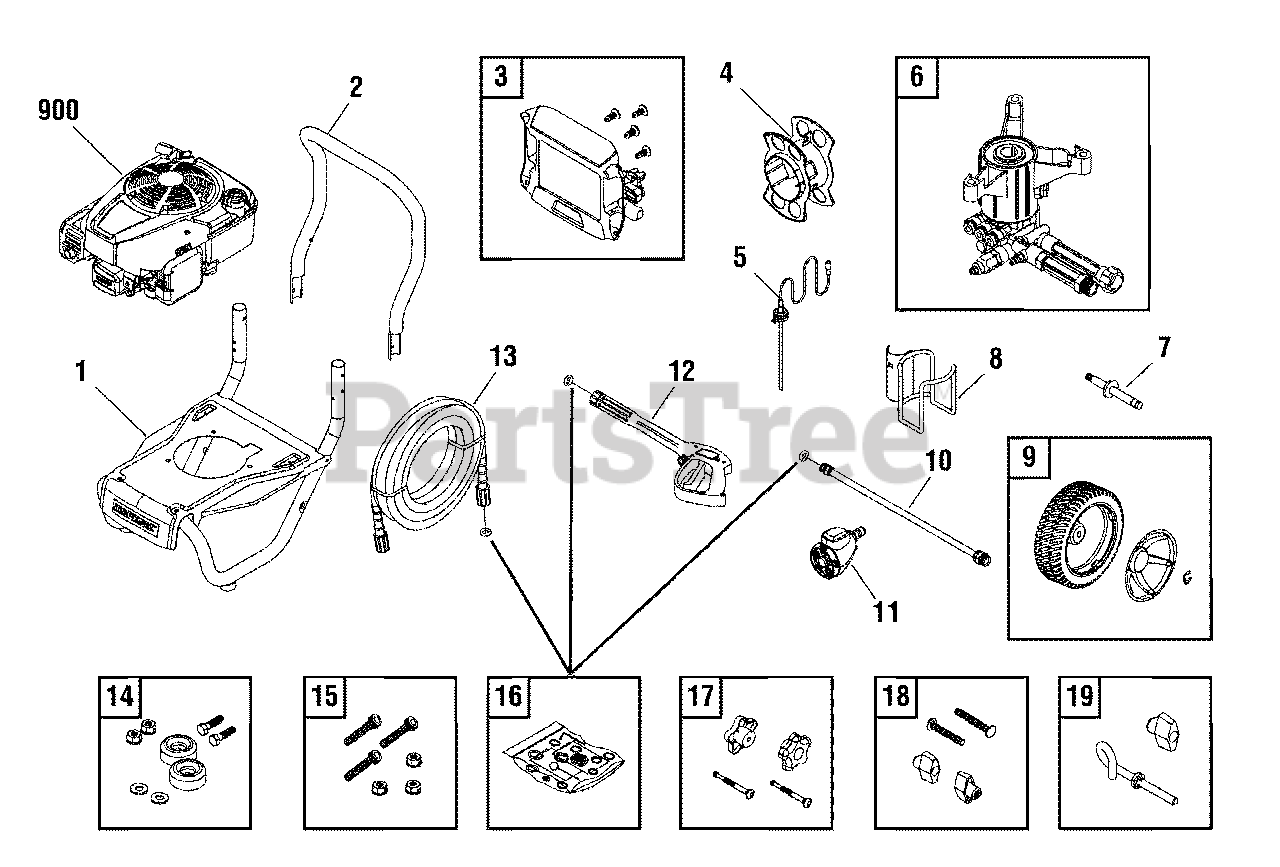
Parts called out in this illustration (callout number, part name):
1	BASE
6	PUMP
7	AXLE
10	EXTENSION, QC
11	NOZZLE, QC
12	GUN
13	HOSE
14	MOUNT, Vibration
15	KIT, Hardware, Pump Mounting
16	KIT, O-Ring
17	KIT, Hardware, Handle
18	KIT, Hardware, Handle
